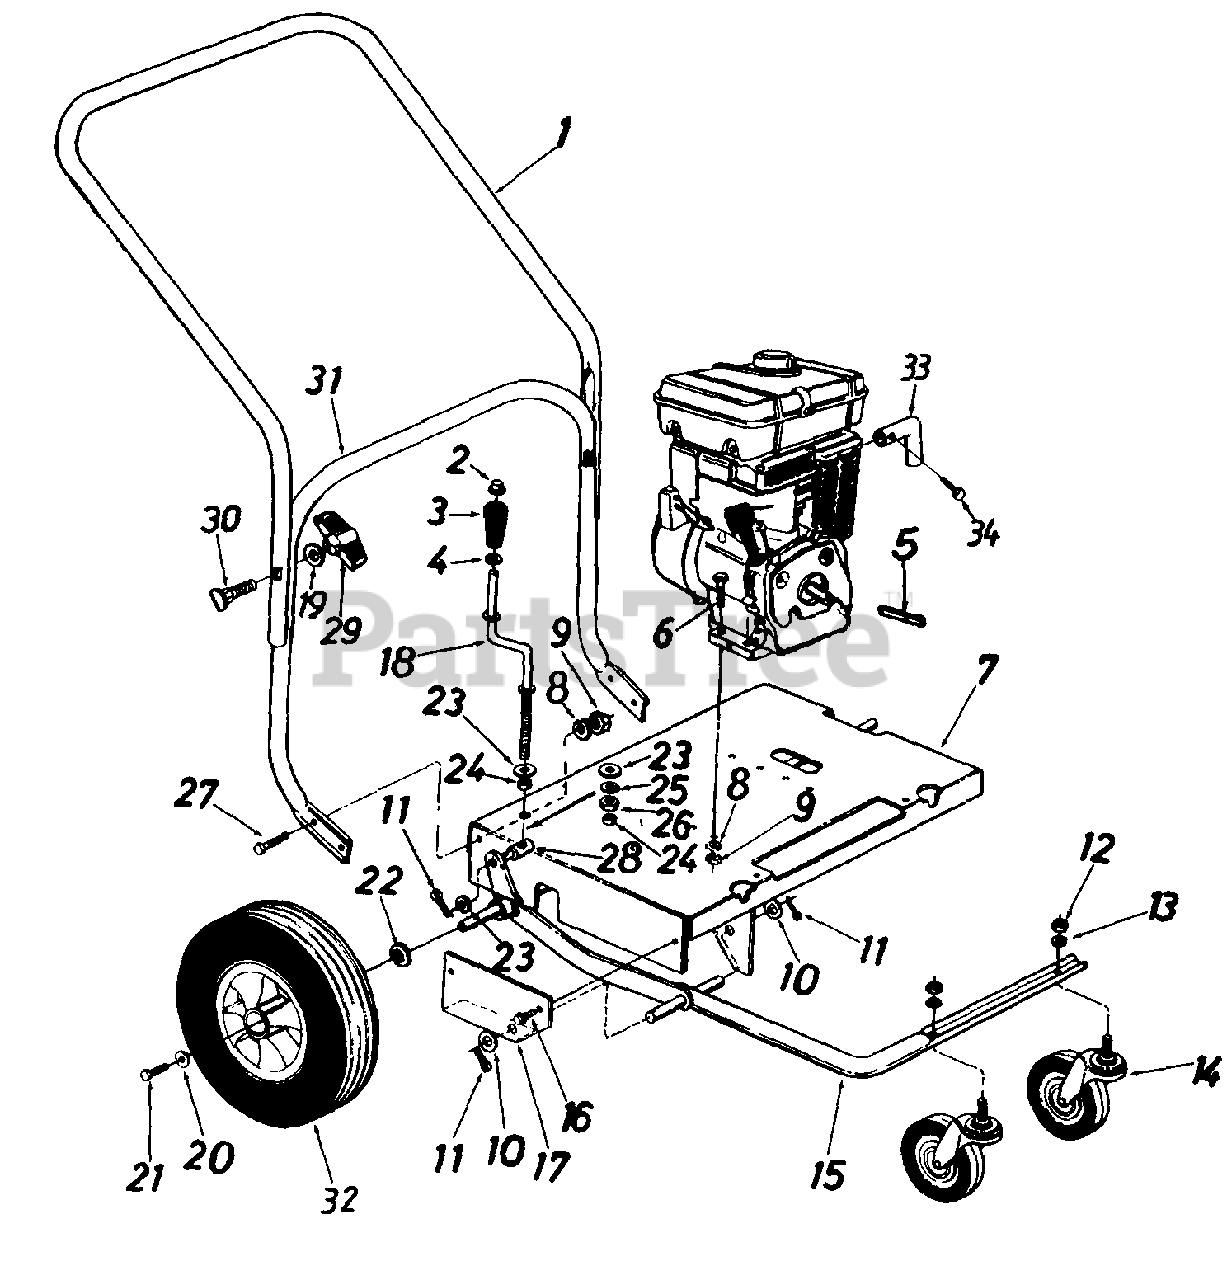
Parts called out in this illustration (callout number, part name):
2	Push Nut 3/8" Rod
3	Crank Knob
4	Fl-Wash .385" I.D. x .62"
5	Sq. Key 1/4" x 2.0" Lg.
6	Hex Bolt 5/16-18 x 1.50" Lg.
9	Hex Nut 5/16-18 Thd.
10	Fl-Wash .63" I.D. x 1.25"
11	Cotter Pin 1/8" Dia. x 1.0"
12	Hex Nut 1/2-13 Thd.
13	L-Wash. 1/2" I.D.
14	Swivel Caster Wheel 5" Dia. x 1.25"
19	Saddle Wash .32" 1.0. x .93"
20	Fl-Wash .34" I.D. x .87" O.D.
21	Hex L-Bolt 5/16-24 x .64" Lg.
22	Fl-Wash.
23	Fl-Wash .38" I.D. x .57"
24	Spacer .382" I.D. x .50" x .180" Lg.
25	L-Wash. 3/8" I.D.
26	Hex Nut 3/8-8 Thd.
27	Hex Bolt 5/16-18 x .75" Lg.
28	Ferrule
29	Hand Knob
30	Carriage Bolt 5/16-18 x 2.0"
33	Outlet Pipe
34	Hex Wash. Hd. AB-Tap Scr. #8 x .5" Lg.
